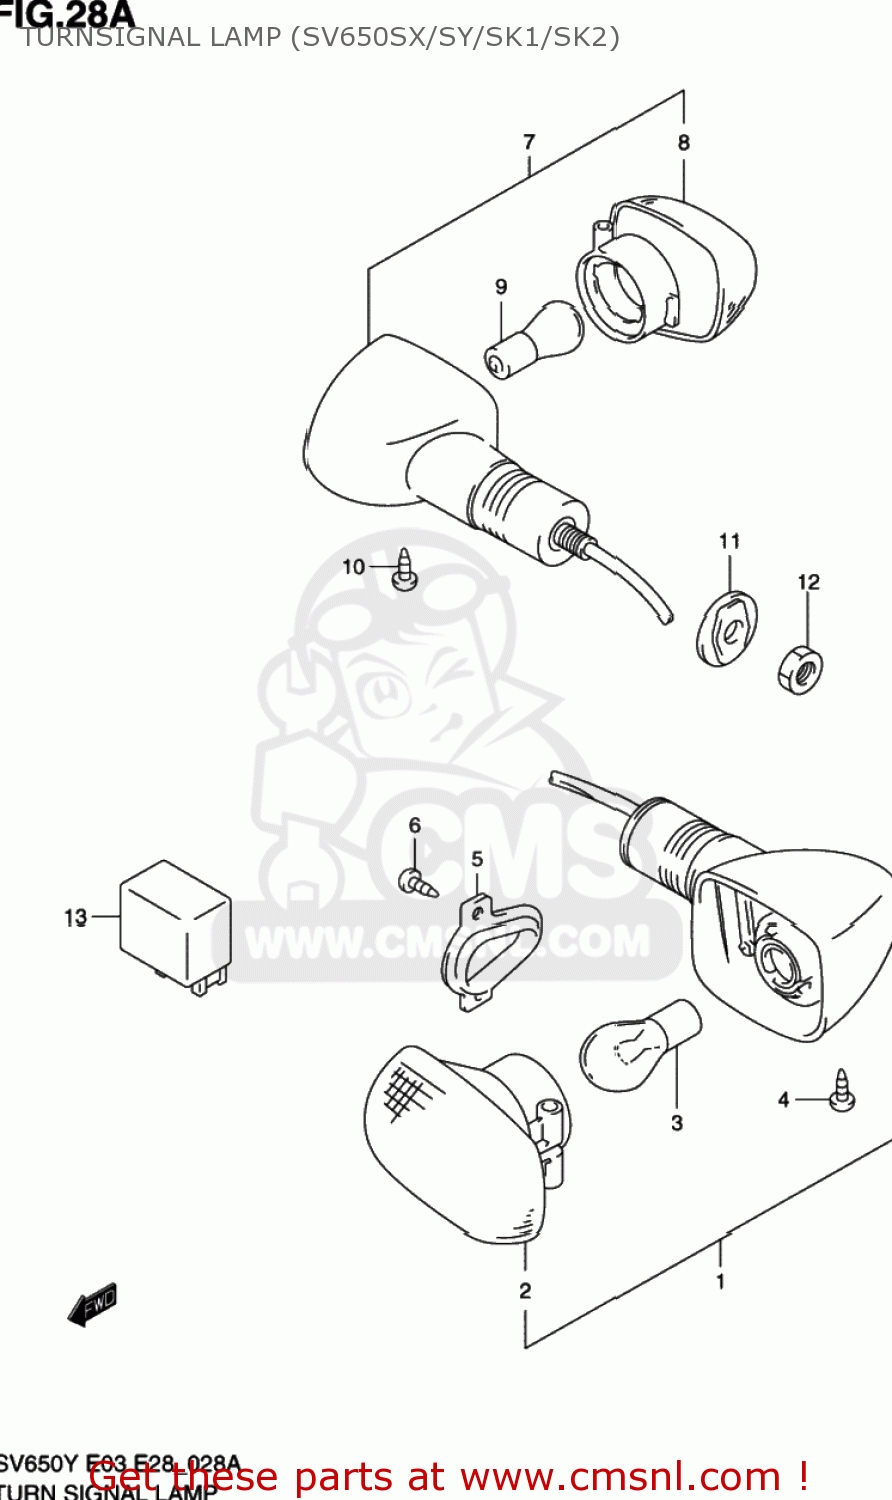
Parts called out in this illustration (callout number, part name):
1	LAMP ASSY,FR TURN SIGNAL,R
2	LAMP UNIT
3	BULB(12V21W)
4	SCREW
5	PLATE,FR TURNSIGNAL LAMP
6	SCREW
7	LAMP ASSEMBLY,REAR TURN SIGNAL
8	LAMP UNIT
9	BULB(12V21W)
10	SCREW
11	SPACER,RR TURNSIGNAL
12	NUT
13	RELAY ASSY,TURNSIGNAL LAMP
